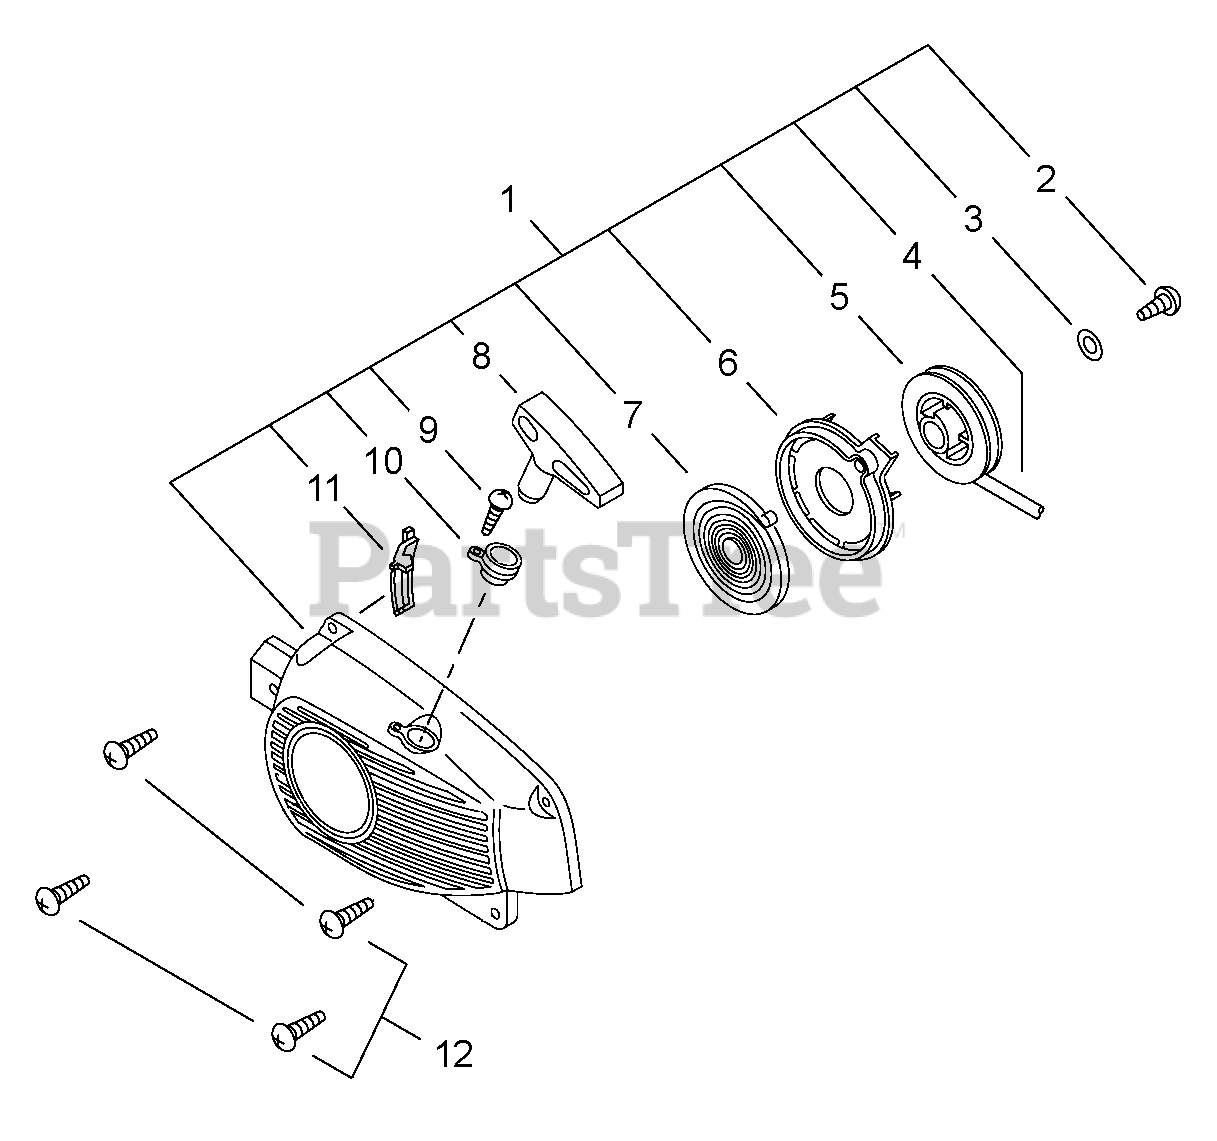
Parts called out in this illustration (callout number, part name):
1	STARTER ASSY, RECOIL
2	SCREW 4×14
3	WASHER 4.1×15.5×1T
4	ROPE, STARTER 3.0×850
5	REEL, ROPE
6	PLATE, STARTER
7	SPRING, RECOIL
8	GRIP, STARTER
9	SCREW 3×14
10	GUIDE, ROPE
12	SCREW 4×16
